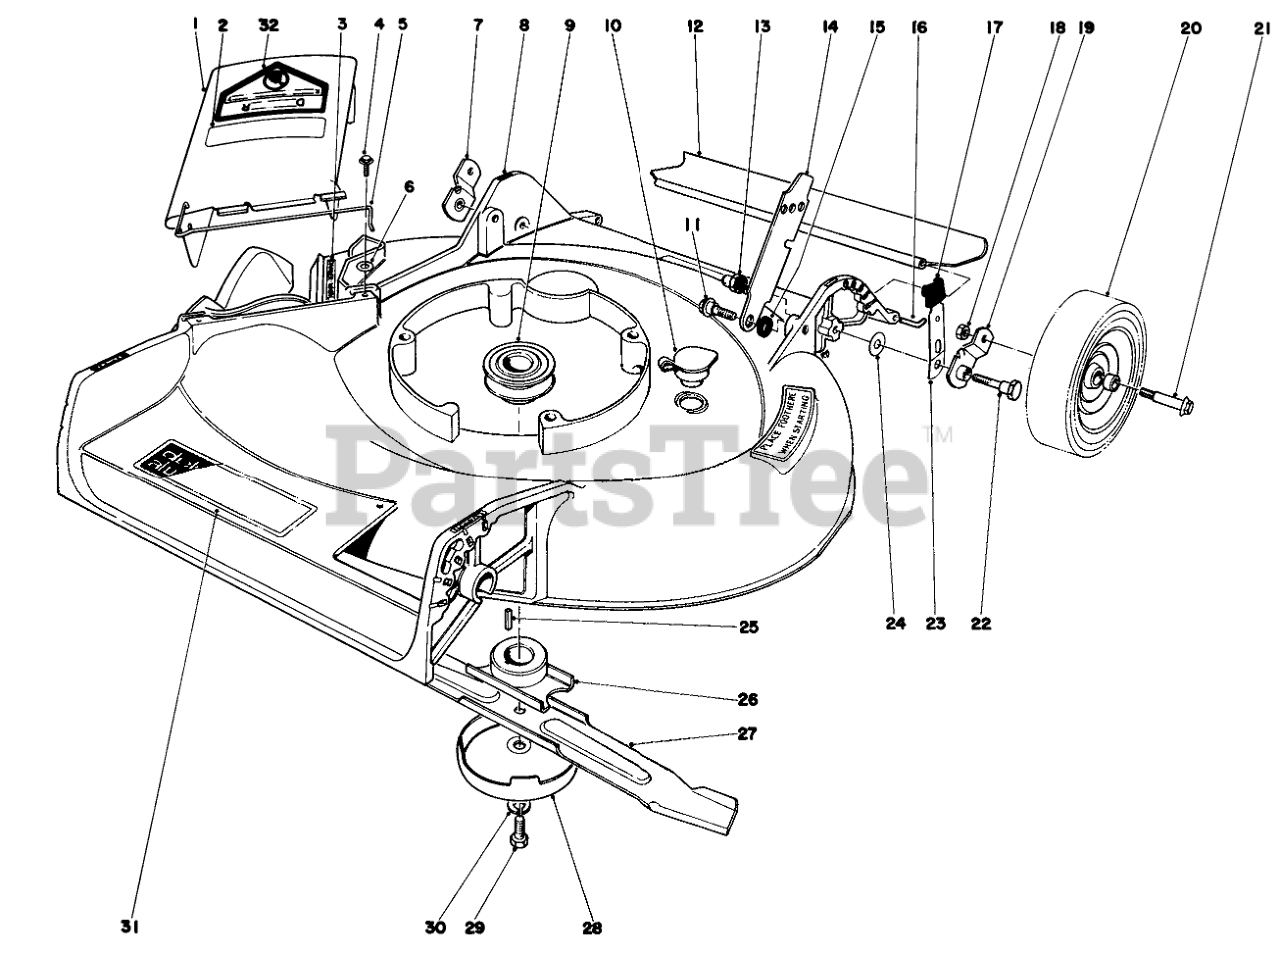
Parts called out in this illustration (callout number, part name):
1	Deflector Cover Assembly (Incl. Ref. #2, 5, & 32)
2	Decal-Caution
3	Decal
4	SCREW
5	SPRING HINGE
6	WASHER-FLAT
7	Pivot Arm
8	Housing
9	DRIVER PULLEY
10	Plug Washout
11	SCREW-SHOULDER
12	Rear Shield
13	HANDLE PIVOT NUT
14	Latch
15	SPACER
16	SHIELD ROD
17	KNOB-ARM
18	Nut
19	Pivot Arm
20	Wheel & Tire Assy. (Incl.Ref. #33)
21	BOLT-WHEEL
22	5/16-18 PIVOT SCREW
23	SPRING ARM ASM
24	WASHER-PIVOT
25	KEY-SQUARE
26	Blade Retailer
27	Blade
28	AntiScalp Cup
29	SPECIAL SCREW
30	WASHER-LOCK
31	Decal-Deck
32	DECAL-DANGER
